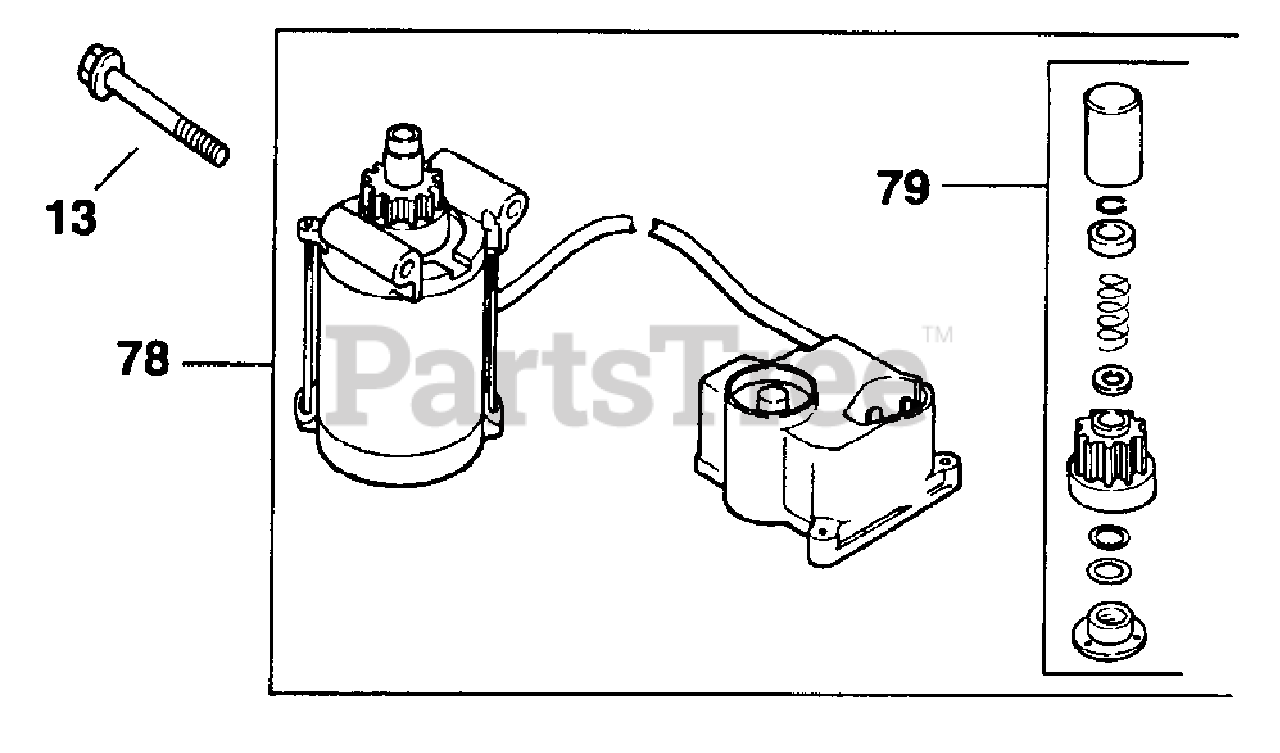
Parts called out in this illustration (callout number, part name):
13	SCREW - USE M-839070
78	STARTER - USE 12 098 16
79	KIT, DRIVE - DISCONTINUED
